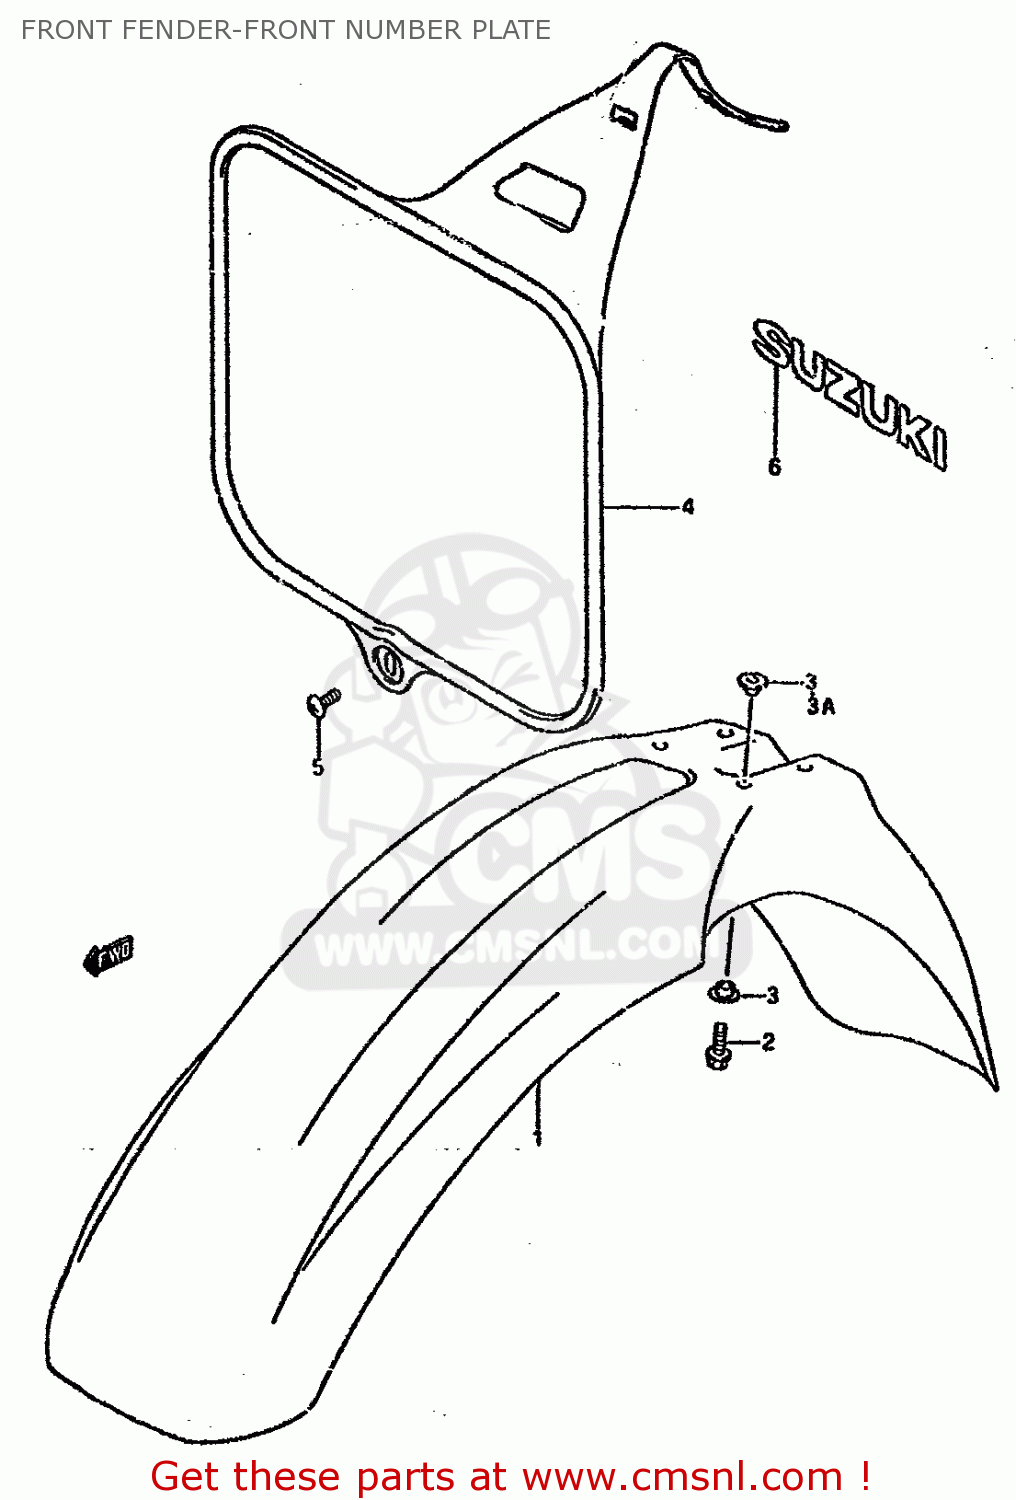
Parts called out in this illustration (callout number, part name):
1	FENDER,FRONT
2	BOLT
3	WASHER
3A	WASHER
4	PLATE,NUMBER,FRONT
5	SCREW
6	EMBLEM, SUZUKI
